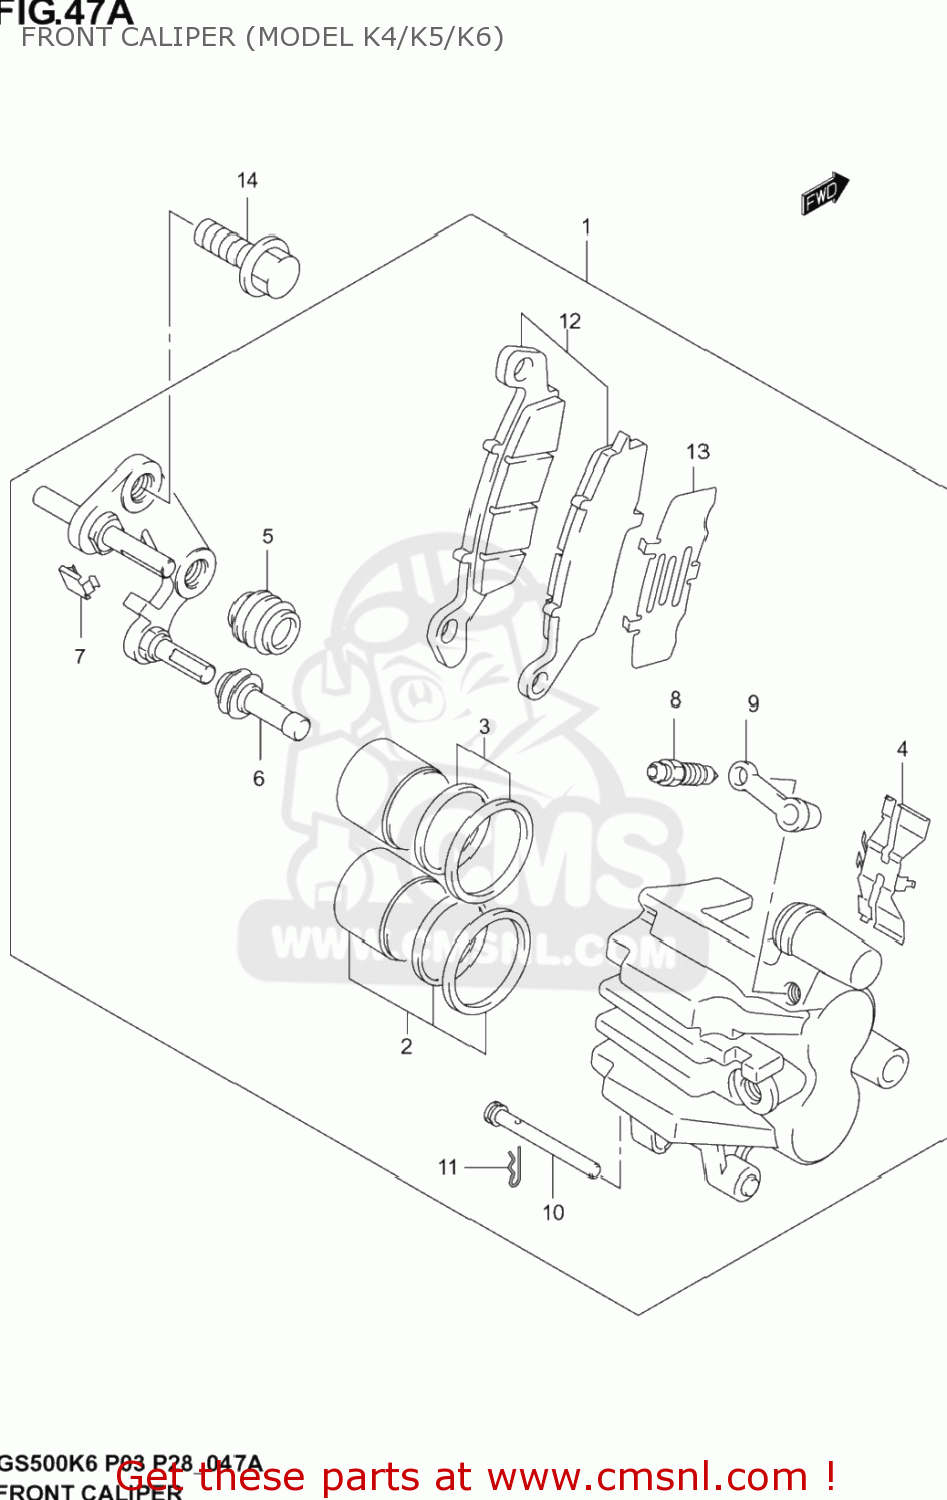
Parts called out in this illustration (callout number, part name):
1	CALIPER ASSY,F
2	PISTON SET
3	SEAL SET PISTO
4	SPRING
5	BOOT
6	INSULATOR
7	GUIDE
8	BLEEDER
9	CAP
10	PIN
11	CLIP
12	PAD & SHIM SET (NAS)
13	SHIM,PAD
14	BOLT
